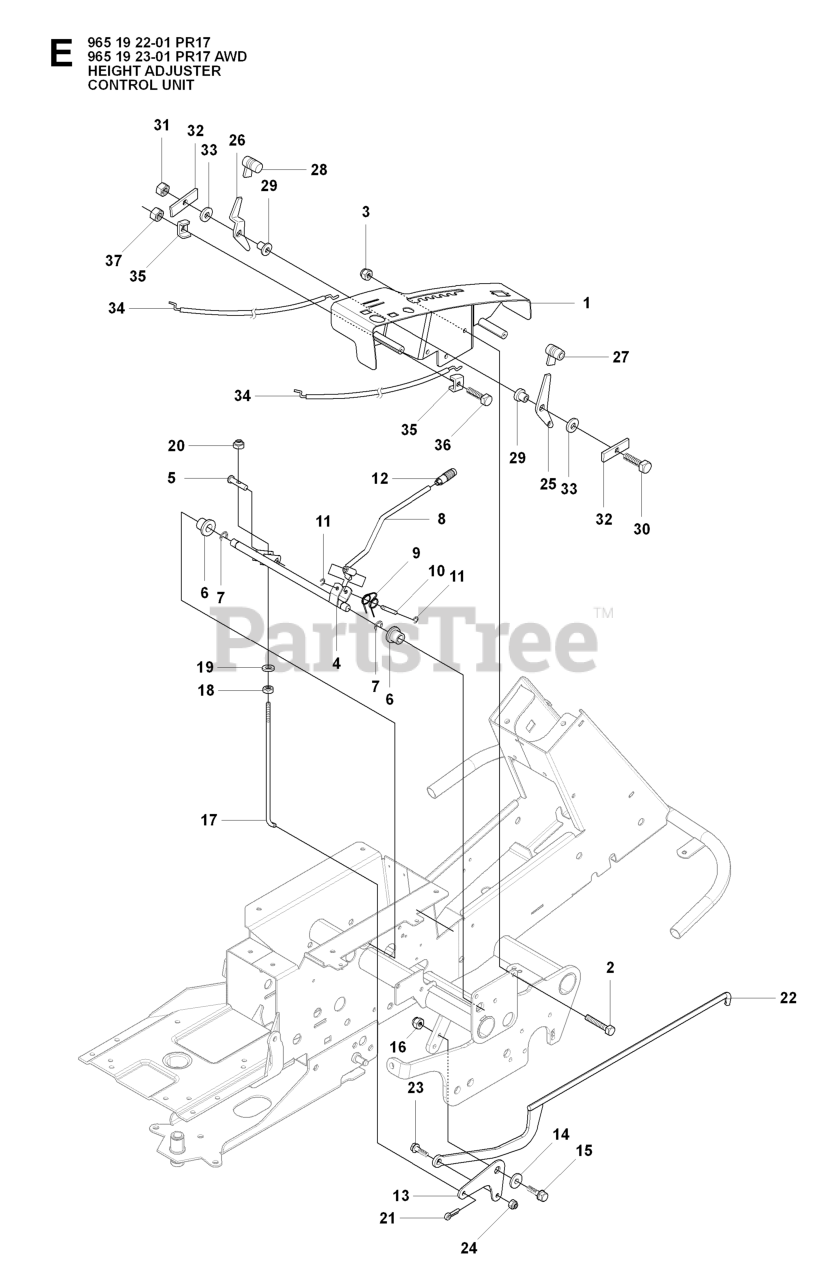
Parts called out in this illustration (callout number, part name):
3	LOCKNUT M8
6	BUSHING
9	HAIR PIN SPRING
12	GEAR STICK KNOB
14	WASHER
16	LOCKNUT M6
18	NUT
19	WASHER
20	LOCKNUT M8
24	NUT
30	SCREW M6S 6X30
31	LOCKNUT M6
33	SPRINGWASHER
37	LOCKNUT M5
